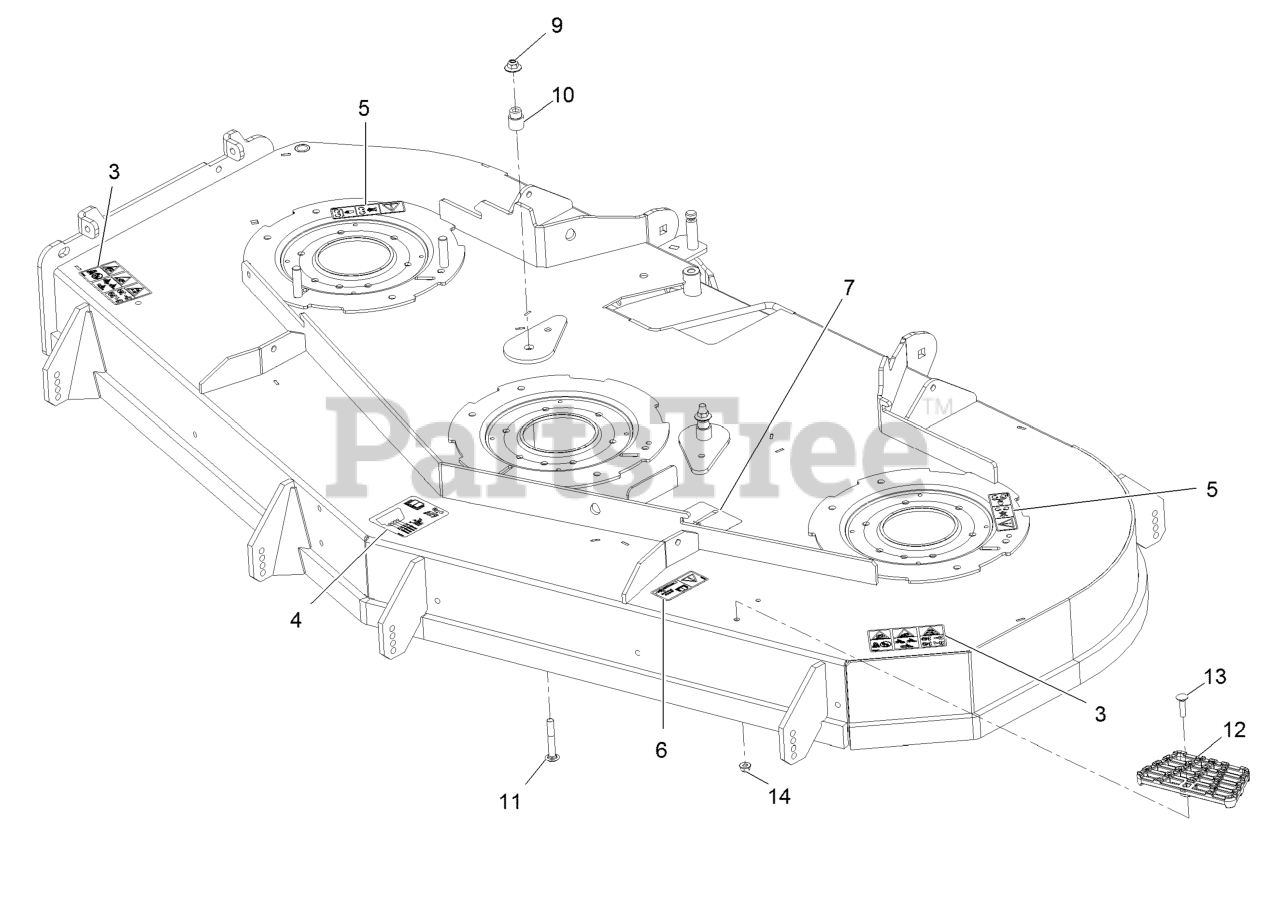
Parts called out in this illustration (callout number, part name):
3	Decal-Danger Thrown Objects
4	Decal-Roller, Anti-Scalp
5	Decal-Cover, Missing
6	Decal-Bolt Torque
7	Decal-Belt Routing
9	Nut-Flange, NI
10	Bushing, Idler
11	Screw-CARR
12	Step-Deck
13	Screw-CARR
14	Nut-HF, NI
